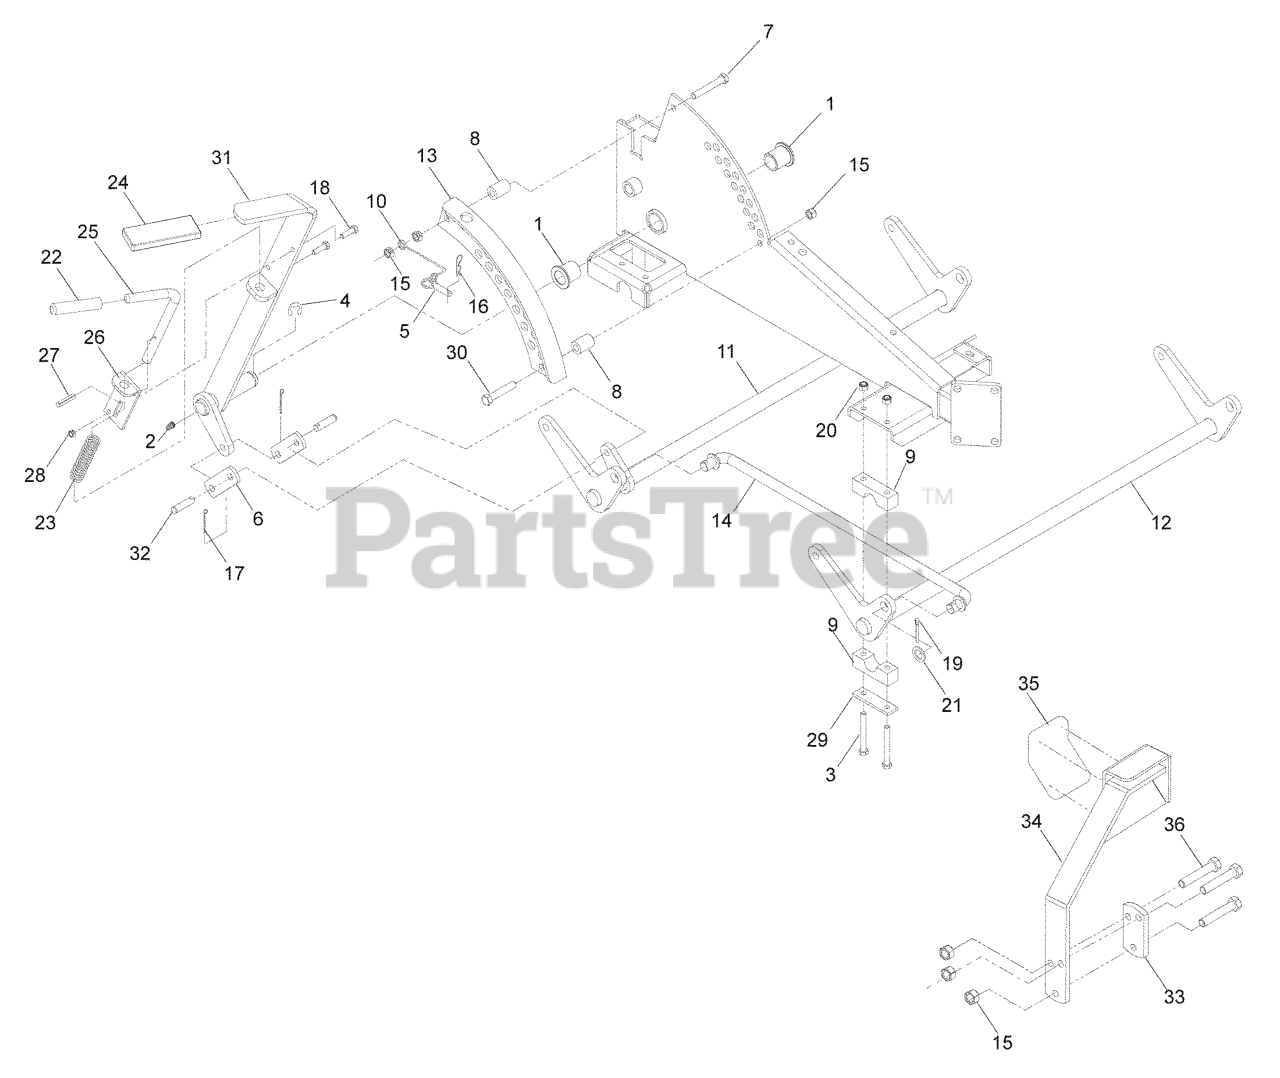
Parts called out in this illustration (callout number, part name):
1	BUSHING, FLANGED
2	ZERK
3	HCS 5/16C X 2-3/4
4	E-RING 7/8
7	SCREW 3/8C X 2 3/4 HEX CAP
8	DECK LIFT SPACER
9	PILLOW BLOCK
11	REAR LIFT SHAFT
12	FRONT LIFT SHAFT
13	ADJUSTMENT PLATE WLDMT
14	CROSS LINK
15	NUT 3/8-16 NYLOC
16	HAIRPIN #4
17	RP_COTTER PIN 1/8 X 3/4
18	HCS 1/4C X 3/4 HCS
19	COTTER PIN
20	5/16-18 NYLOC FLANGE NUT
21	BUSHING
26	PIN MT, UPPER
28	NUT 1/4C CENTER LOCK
29	REINFORCEMENT BAR
30	HCS 3/8C X 2 1/2
31	LIFT LEVER WELDMENT
32	CLEVIS PIN 3/8 X 1 1/8
33	TIGHTENING PLATE BLK
34	LIFT PEDAL BLK
35	ANTI-SKID PAD
36	HCS 3/8C X 1 1/2
